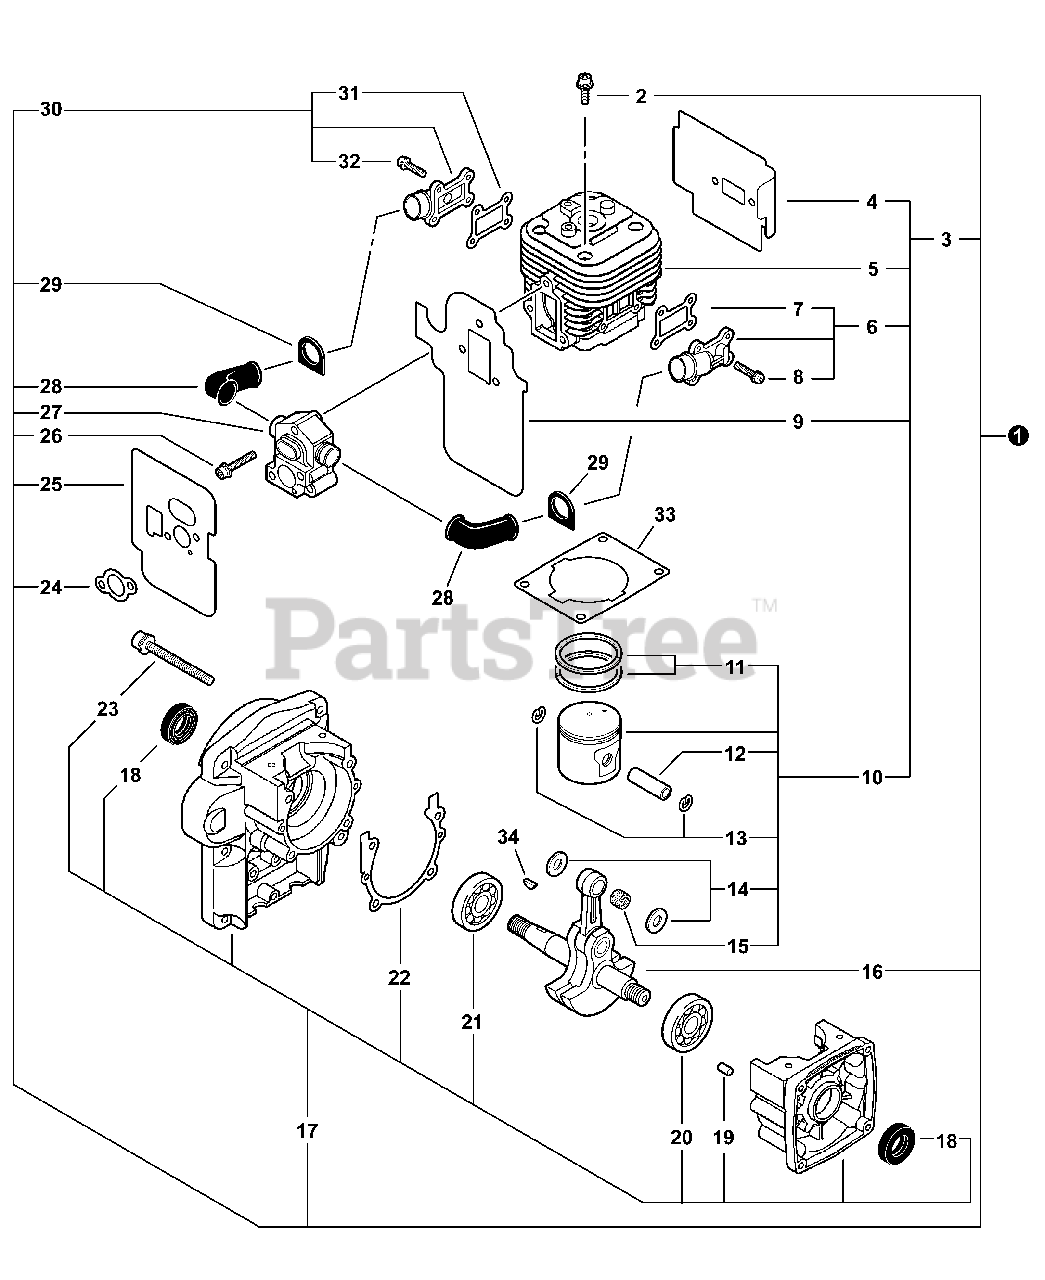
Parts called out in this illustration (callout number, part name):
1	SHORT BLOCK -- SB1111
2	SCREW - 5×22
3	CYLINDER/PISTON KIT
4	SHIELD, EXHAUST
5	CYLINDER
6	REED VALVE KIT - OUTER
7	GASKET, INTAKE
8	SCREW - 4
9	GASKET, INTAKE
10	PISTON KIT
11	RING, PISTON
12	PIN, PISTON
13	RING, RETAINING - 8
14	WASHER - 10
15	BEARING, NEEDLE - 10
16	CRANKSHAFT ASSY
17	CRANKCASE KIT
18	SEAL, OIL
19	PIN - LOCATING
20	BEARING, BALL - 6202
21	BEARING, BALL - 6302C3
22	GASKET, CRANKCASE
23	SCREW - 5×40
24	GASKET, INTAKE
25	SHIELD, INTAKE
26	SCREW - 5×35
27	VALVE ASSY
28	HOSE, AIR
29	GROMMET
30	REED VALVE KIT - INNER
31	GASKET, INTAKE
32	SCREW - 4
33	GASKET, CYLINDER
34	KEY - 3×14
